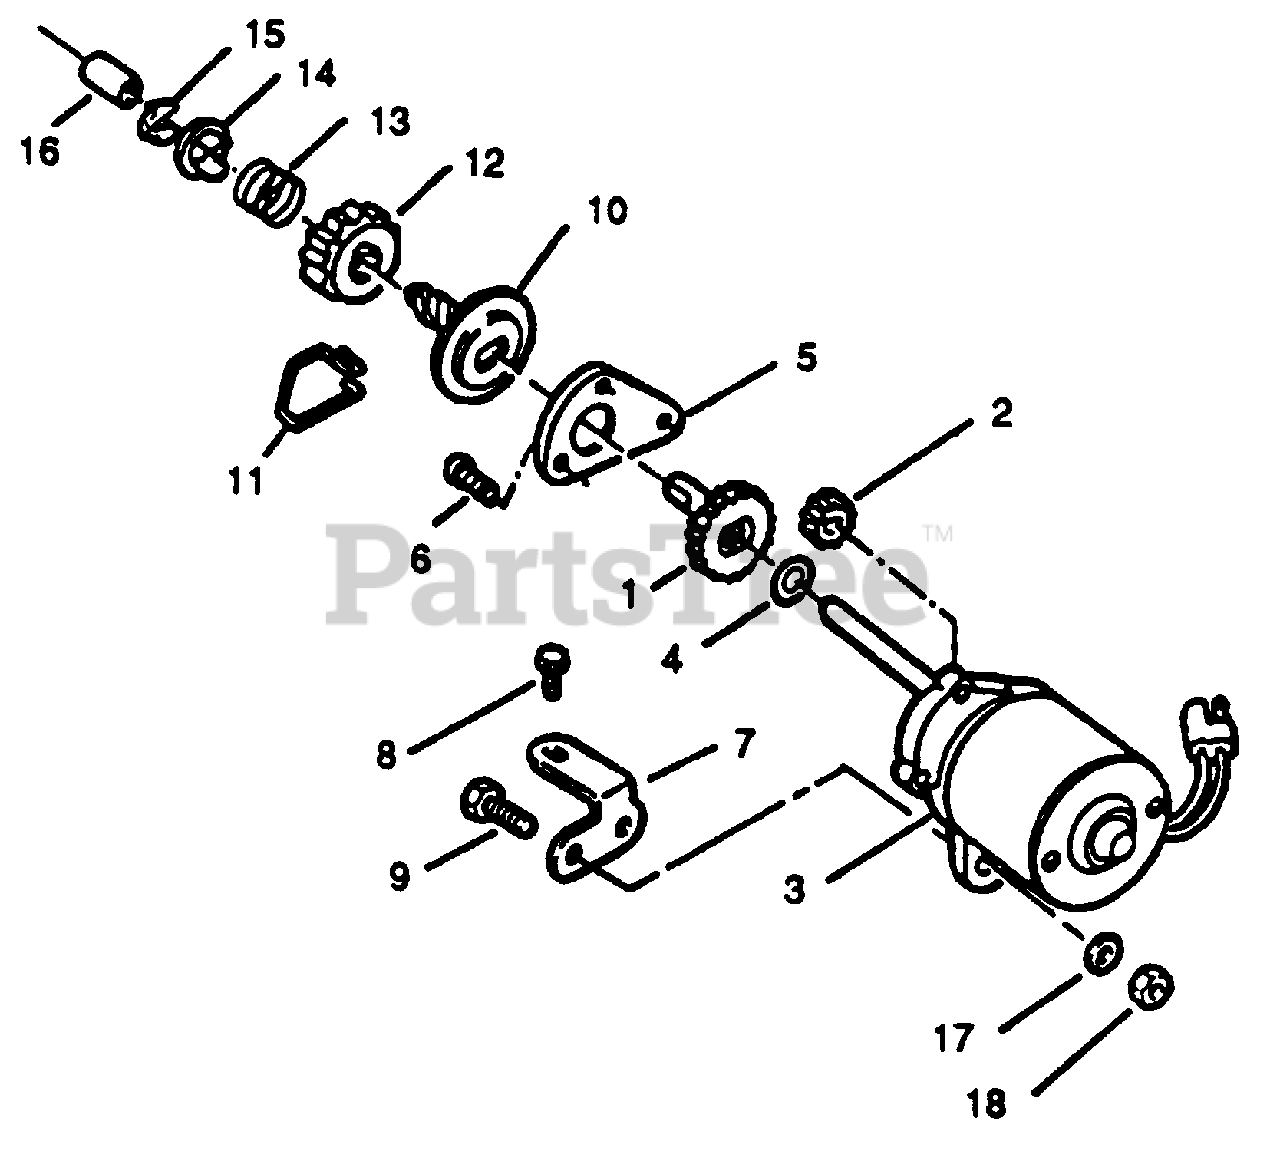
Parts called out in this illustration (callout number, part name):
1	Gear-Driven
2	Pinion-Motor Shaft
3	Motor Housing & Pin Assembly
4	Washer
5	Plate-Gear Cover
6	Screw
7	Bracket-Starter Mounting
8	Screw
9	Screw
10	Pinion, Spring & Clutch Ass'y (Inc. 11-15)
11	Spring-Drag
12	Pinion
13	Spring-Pinion Return
14	Washer-Pinion Stop
15	Retaining Ring
16	Sleeve
17	Lockwasher
18	Nut
